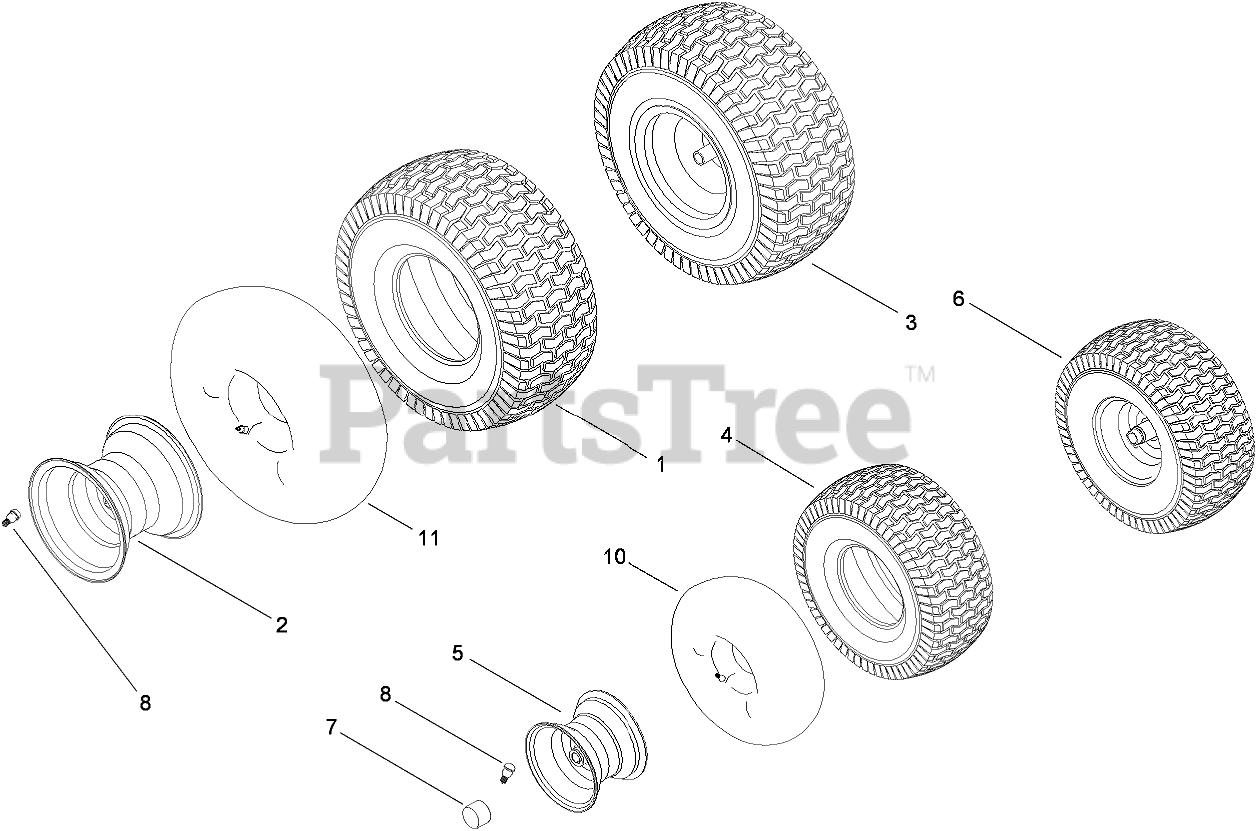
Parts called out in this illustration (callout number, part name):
1	TIRE-TURF
2	RIM-WHEEL, REAR
3	WHEEL ASM
4	TIRE-FRONT
5	Rim-Wheel, Front
6	Front WHEEL ASM
7	CAP-HUB
8	VALVE-AIR, TUBELESS
10	TUBE-INNER
11	TUBE-INNER
